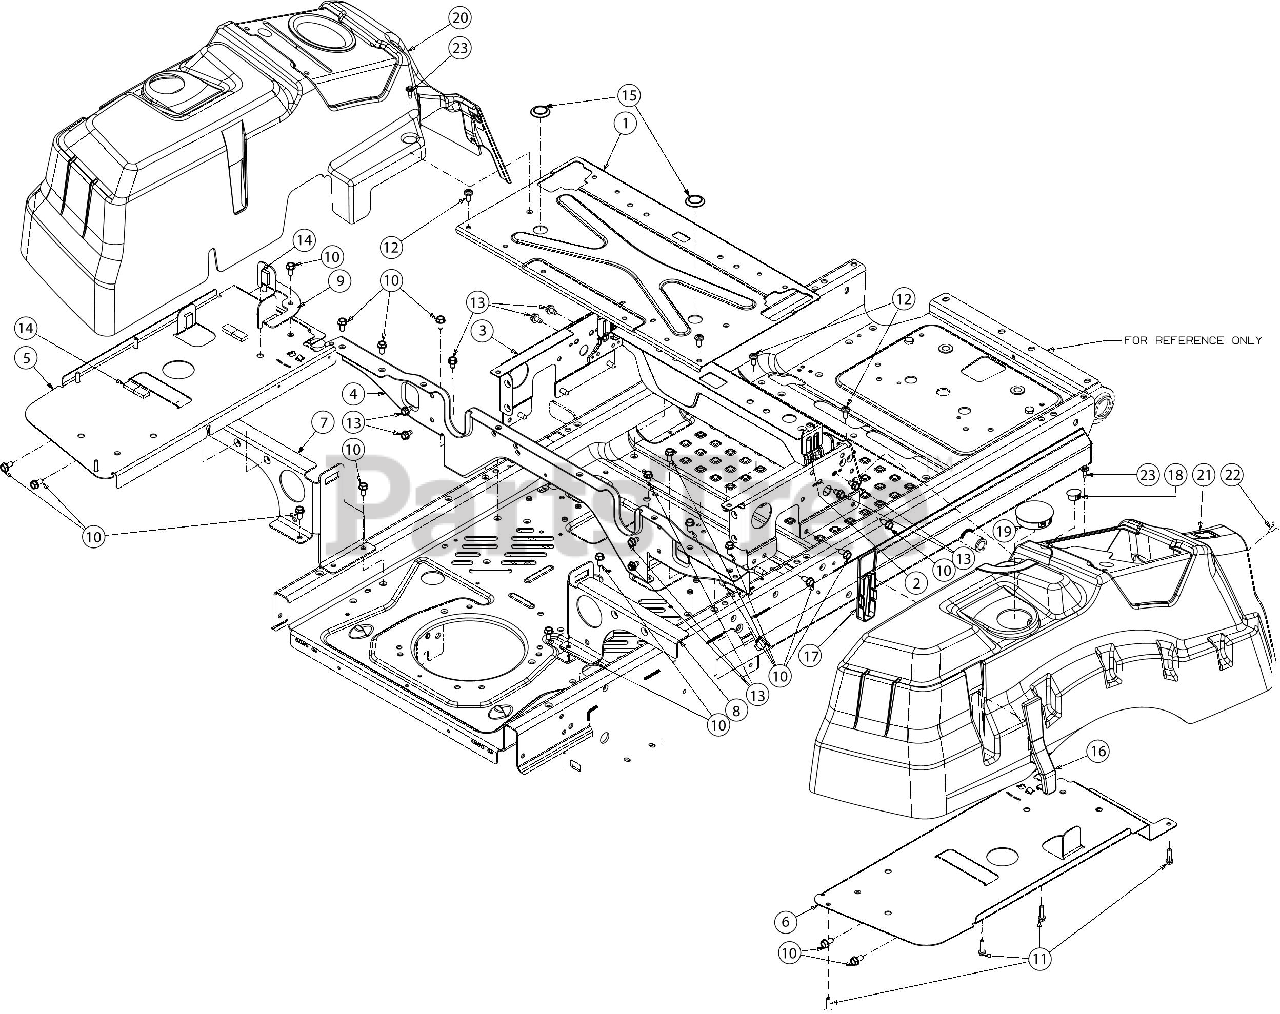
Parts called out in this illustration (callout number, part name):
10	SCREW 5/16-18 X .750
11	SCREW 5/16-14 X 1
12	SCREW 5/16-18 X .750
13	SCREW 5/16-18 x .500
14	FOAM TAPE .625 WIDE X .25 THK BULK
16	CONSOLE PLUG (RH) OUTER
17	CONSOLE PLUG (RH) INNER
18	CONSOLE PLUG (RH)
19	FUEL NECK PLUG
20	CONSOLE (LH) 2.25 CAP"
21	CONSOLE (RH) 2.25 CAP"
22	TORX SHOULDER SCREW 1/4-20
23	SHOULDER SCREW M6-1 .368 X.115
